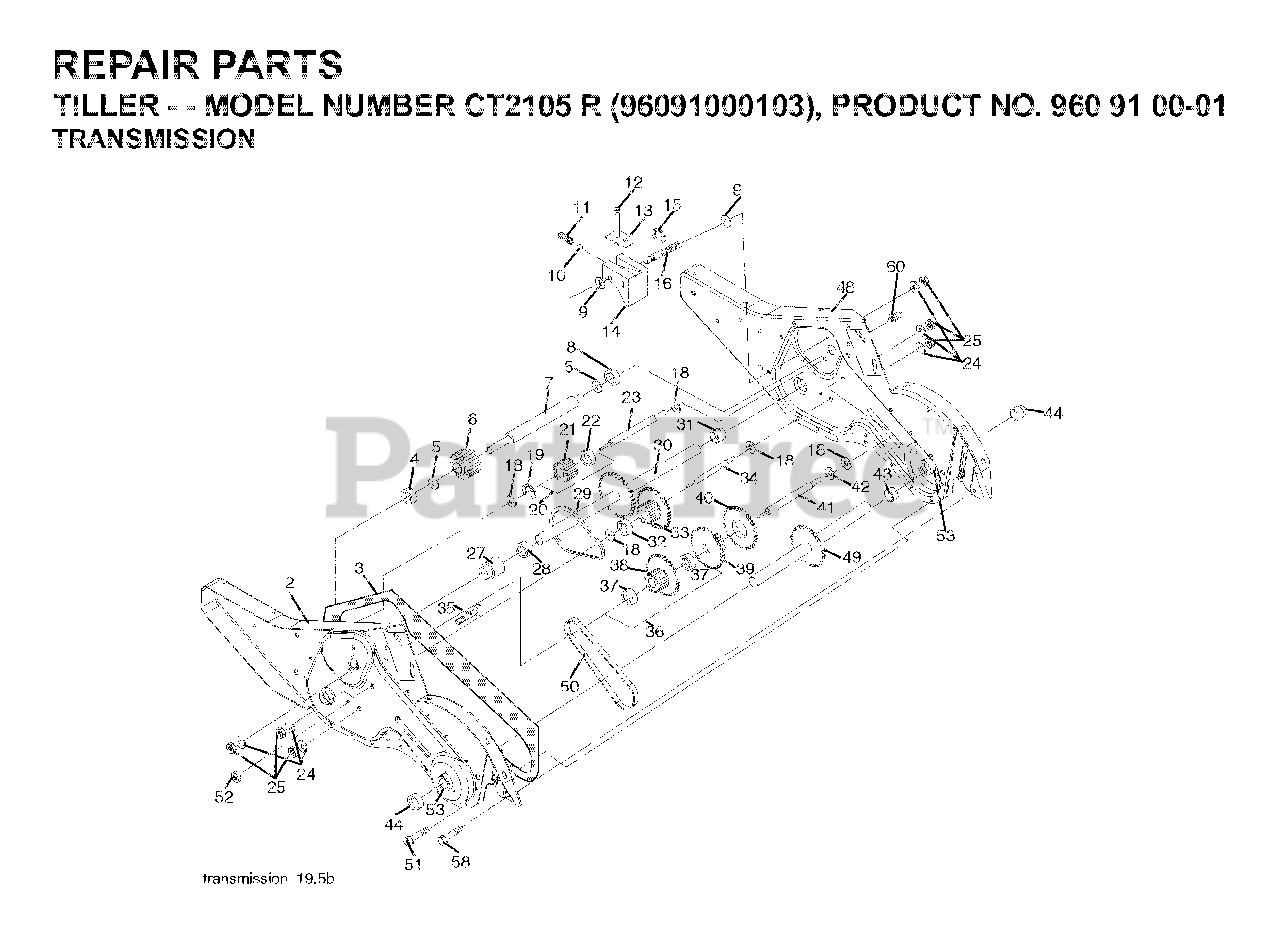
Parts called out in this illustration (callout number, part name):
1	TRANSMISSION ASM.
2	GEARCASE.ASM.CRT.LH.W/BEARING
3	GASKET
4	NEEDLE BRNG LT
5	THRUST WASHER
6	GEAR.PINION.INPUT
7	SHAFT.INPUT."D".TILLER
8	BEARING TI
9	WASHER, SEAL
10	STEEL BALL KIT
11	SPRING-SHIFT CRT
12	O-RING TI
13	SHIFTING ARM
14	SHIFT FORK TI
15	KLIP RING
16	SHAFT.SHIFTER.TILLER
19	KLIP RING
20	GEAR ASSY CRT
21	GEAR-REV IDLR CRT
22	NEEDLE BEARING TI
23	SHAFT CRT
24	LOCKWASHER
27	BEARING, SHAFT LH CRT
29	CHAIN CRT
30	GROUND SHAFT ASS'Y
31	BEARING, SHAFT RH CRT
32	SPACER TI
33	SPRCKT 8 GEAR CRT
34	SHAFT.SECONDARY.REDUCTION.CRT
35	SCRW WHIZ LOK CRT
36	SPROCKET ASS'Y W/BRG
37	BEARING
38	SPROCKET, TINE
39	GEAR TI
41	SHAFT.REDUCTION.TILLER
42	BRNG RACE T
43	SPACER TI
44	SEAL ASM, OIL
48	GEARCASE.ASM.CRT.RH.W/BEARING
49	TINE SHAFT
50	CHAIN.TILLER
51	SCREW
53	BEARING KIT
58	BOLT SHOULDER 1/4-20 UNC X.875
60	FITTING.GREASE.TAPERED
